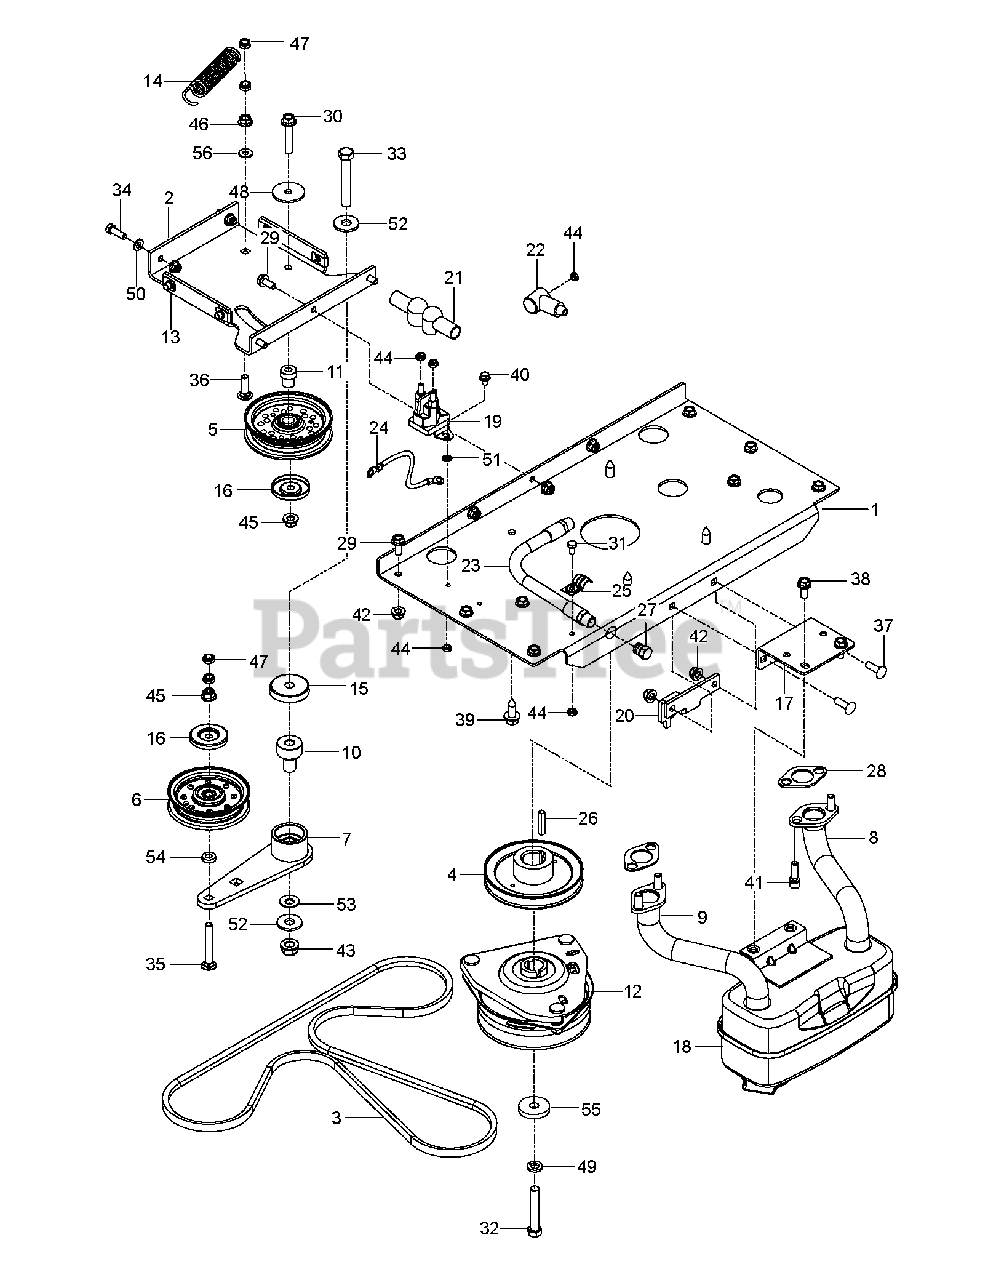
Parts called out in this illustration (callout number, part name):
1	PLATE.PNT.ENGINE.E-DIP
2	PLATE.PNT.IDLER.SUPPORT.E-DIP
3	BELT, HYDRO, 3400
4	PULLEY.DRIVE.XMSN
5	IDLER PULLEY
6	PULLEY.IDLER.FLAT.46.PR.DR.
7	ARM, IDLER, STEEL, W/BGS
8	PIPE.EXHAUST.RH.CV18/20
9	PIPE.EXHAUST.LH.CV18/20
10	PIVOT, BEARING
11	PIVOT, IDLER
12	CLUTCH MZ ZTR GT.48/54"1.125"
13	U-CLIP 5/16-18 NUT RETAINER
14	SPRING, PUMP
15	SHIELD, DUST
16	DUST SHIELD
17	BRKT, MUFFLER, BLK
18	MUFFLER ASM TWIN
19	SOLENOID.W/BRASS.PLUNGER
20	BRACKET.CLUTCH.STOP.PNTX431
22	TERMINAL COVER
23	HOSE.ASSEMBLY.OIL.DRAIN
24	CABLE POSITIVE
26	KEY, 1/4 SQ X 1 1/4
27	PLUG OIL DRAIN
28	GASKET
29	HHFS 5/16-18 X 3/4
30	HHFS 3/8-16 X 2.0 GD 5
31	BOLT
32	CLUTCH BOLT7/16-20X2.5 GR596HR
33	HCS 1/2-13 X 3-1/4 GD 5 ZD
34	BOLT.FIN.HEX.5/16-18UNC X 1.00
35	BOLT
36	BOLT.3/8-14X1.25
37	BOLT CRT
38	SCREW
39	SCREW 3/8-16X1
40	RP_SCREW.1/4-20X3/8
41	SCREW.SOCKET HD.5/16-1
42	5/16-18 NYLOC FLANGE NUT
43	NUT, 1/2-13 HEX FLG NYLOC ZD
44	JAM NUT 1/4C (2 2 PW01)
45	NUT 3/8-16 HEX FLG NYLOC ZD
46	NUT 3/8C WHIZ
47	NUT HEX 3/8-16 NYLON, THIN
48	WASHER, 3/8 SPEC
49	WASHER 7/16 LOCK
50	WASHER
51	WASHER 1/4 INT TOOTH
52	WASHER.9/16 X 1 3/8 X 12 GA.
53	CONTACT BELLSPR 1/2
54	WASHER 3/8 X 3/4 X .187 TK
55	SPINDLE WASHER
56	WASHER 3/8 FLAT
